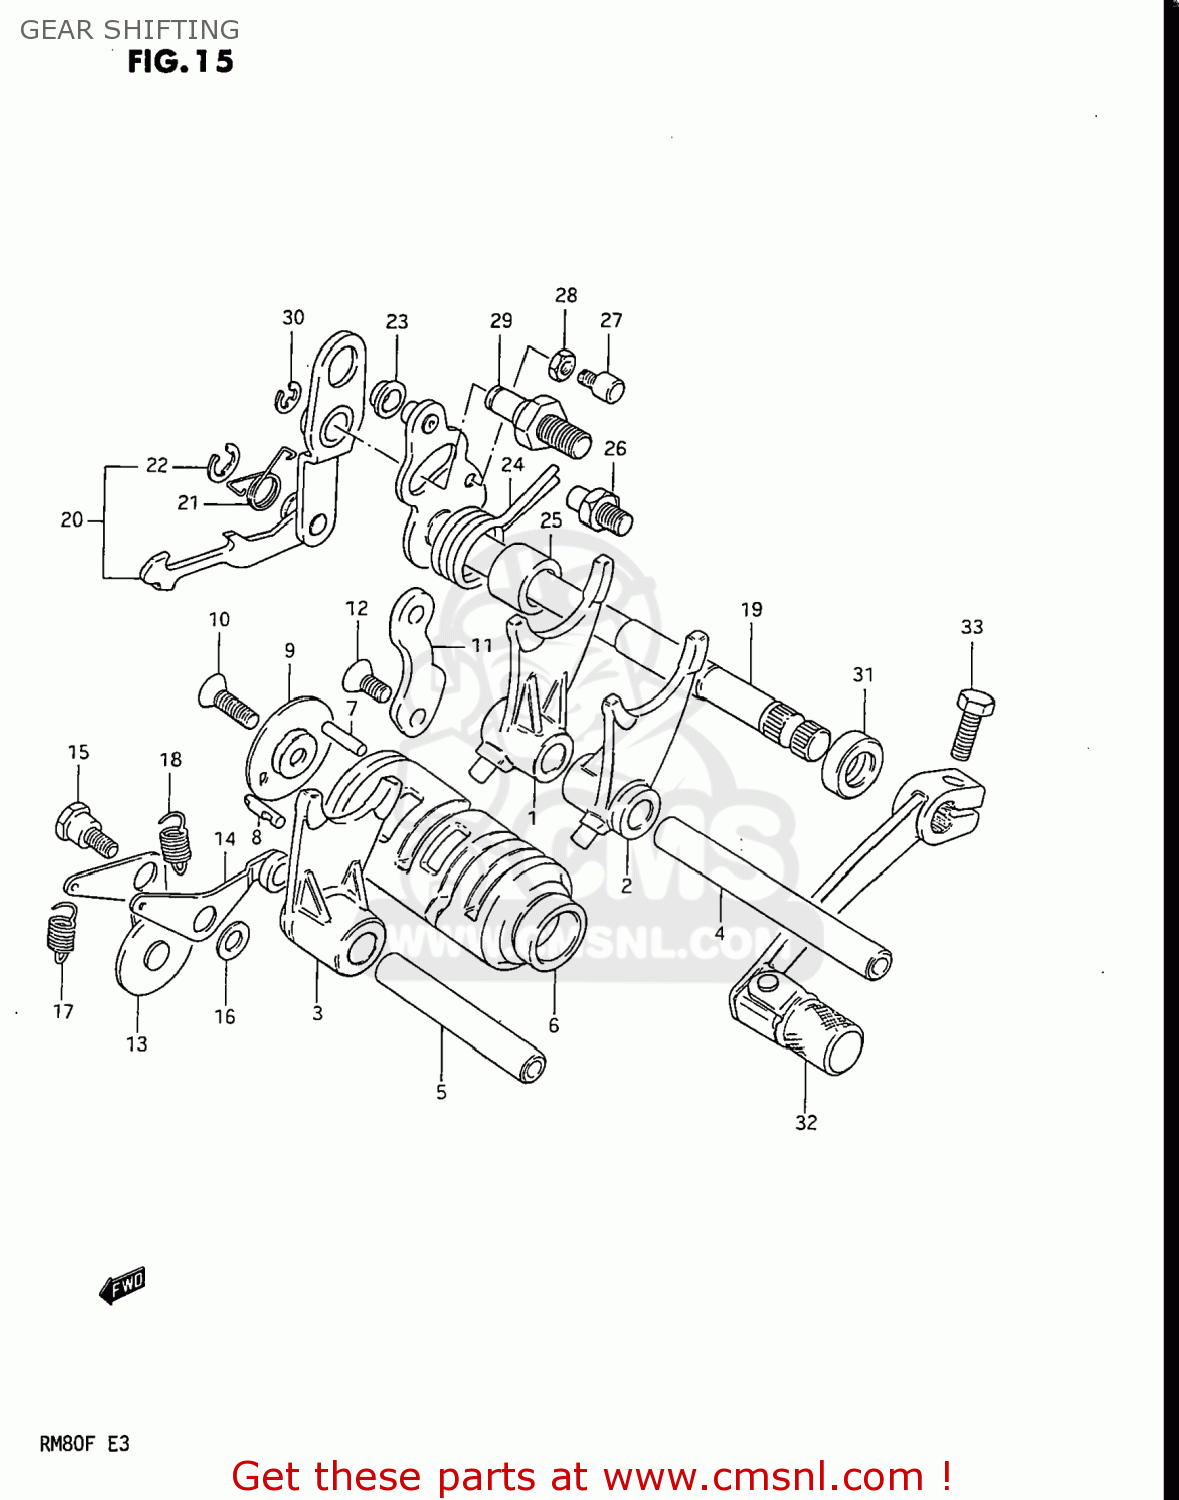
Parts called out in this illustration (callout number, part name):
1	FORK,GEAR SHIFT NO.1
2	FORK,GEAR SHIFT NO.2
3	FORK,GEAR SHIFT NO.2
4	SHAFT,GEAR SHIFT FORK
5	SHAFT,GEAR SHIFT FORK
6	CAM,GEAR SHIFT
7	PIN(4X15.8)
8	PIN
9	RETAINER,GEAR SHIFT CAM
10	SCREW
11	GUIDE,GEAR SHIFTING CABLE
12	SCREW
13	STOPPER,SHIFT CAM
14	STOPPER,GEAR SHIFT CAM
15	BOLT(6X18.3)
16	WASHER
17	SPRING
18	SPRING
19	SHAFT,GEAR SHIFT
20	PAWL,GEAR SHIFT
21	SPRING
22	E RING
23	SPACER(7X10X5)
24	SPRING
25	SPACER(12X20X15.3)
26	STOPPER,GEAR SHIFT CAM
27	BOLT,GEAR SHAFT RETURN SPR SET
28	NUT 6MM
29	STOPPER,GEAR SHIFT CAM
30	E RING 6MM
31	OIL SEAL
32	LEVER ASSEMBLY,GEAR SHIFTING
33	BOLT
